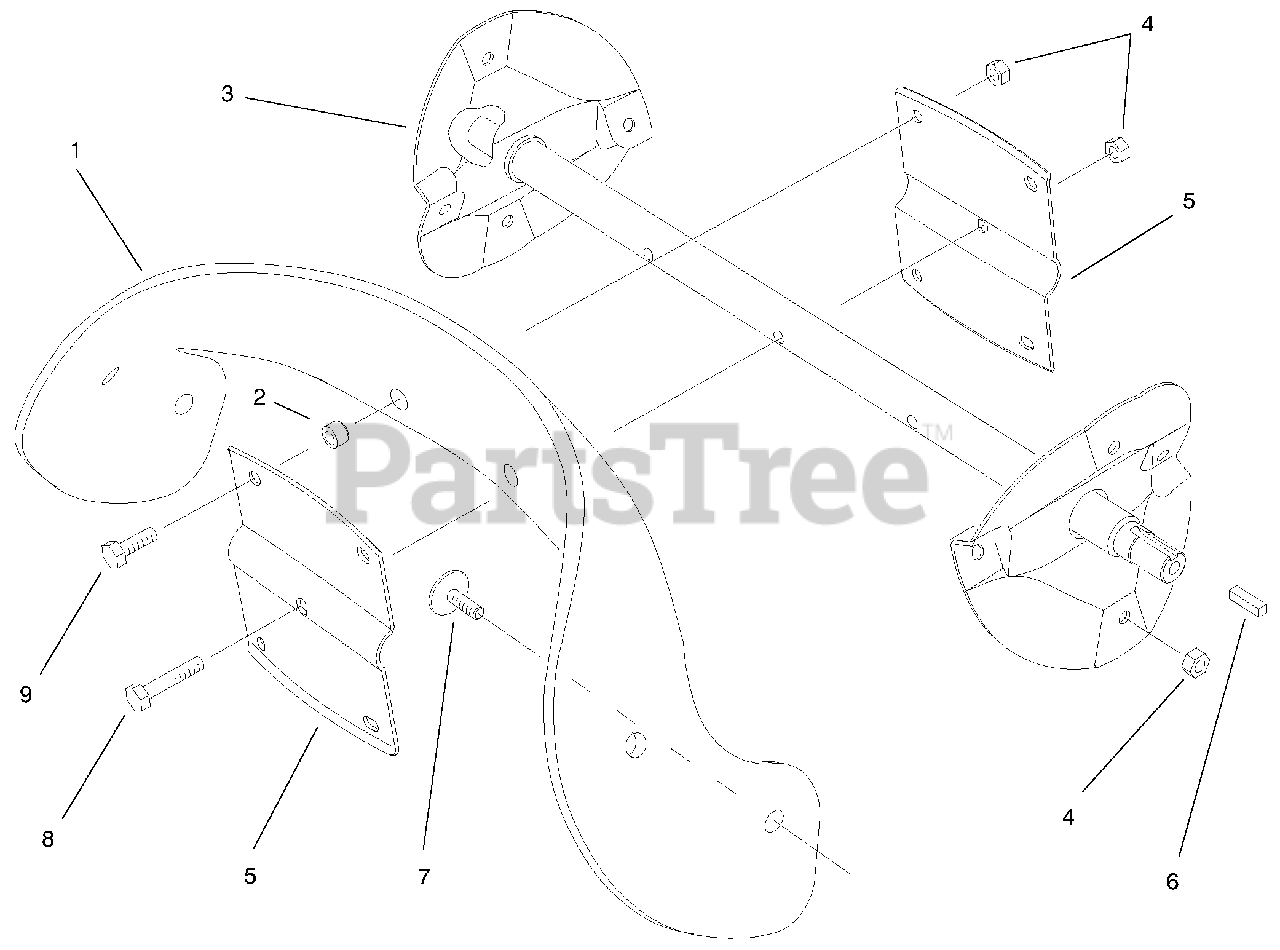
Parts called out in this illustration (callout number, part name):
1	Blade-Rotor
2	Spacer-Rotor Blade
3	Rotor
4	Nut-Lock
7	Screw
8	Screw-HH
9	Screw-HH
